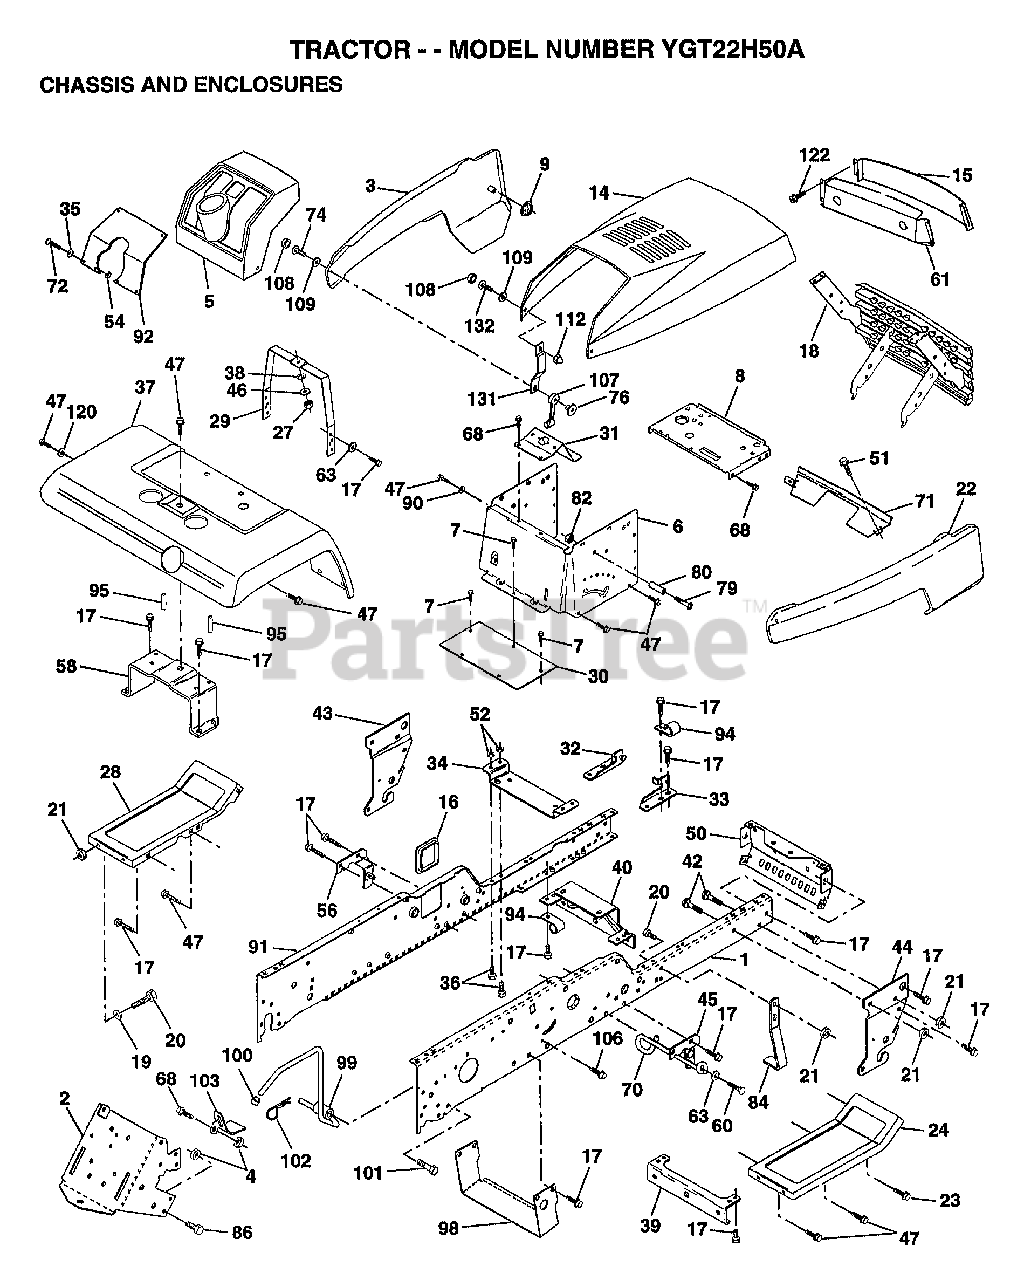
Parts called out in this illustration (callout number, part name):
1	"RAIL,FRAME RH"
2	DRAWBAR GT
3	"PANEL ASM-SIDE,LH"
4	NUT.7/16
5	DASHBOARD BLACK
6	DASH LOWER
7	SCREW
8	SUPPORT.DASH.BTRY
9	PAL NUT LT
14	"HOOD, YARD PRO"
15	LENS.BAR.CLEAR
16	COVER ACCESS
17	SCREW
19	WASHER
20	BOLT
22	"PANEL ASM SIDE,RH"
23	SCREW GTV
24	FOOTREST.RH.LT/GT
28	FOOTREST PNT LH
29	DASH.SUPT.YP/HUSQ
30	SADDLE.HYDRO.95
31	BRAKET.SUPT.STEER
32	BRACKET ASM FRAME
33	BRACKET ASM FRAME
34	BRACKET.ENG.SUPT.
35	WASHER
36	BOLT
37	"FENDER WS,FTK"
38	LOCKWASHER
39	BRACKET.AXLE.FRT.
40	"BRKT SUPPORT,AXLE"
43	BRACKET.SUS.FT.LH
44	BRACKET.SUS.FT.RH
45	BRACKET ASM., SUSP CHASSIS RH
46	WASHER PM
47	SCREW LT
50	"BRKT CHASSIS,FRNT"
51	SCREW CRT
56	BRACKET ASM., SUSP CHASSIS LH
58	BRKT.ASM.FENDER
60	SCREW
61	BEZEL.ASM.
63	WASHER
68	SCREW LT
70	GUIDE.BELT.MID.SP
72	SCREW
74	SCREW
76	WELDNUT
79	SCREW
80	SPACER LT
84	STOP.OVER.CENTER
86	BOLT
90	LOCKWASHER
91	"RAIL FRAME,LH"
92	"PLATE DASH,SLKSCR"
94	CLIP GTV
95	NUT-PUSH YT
98	BRACKET SKID CHAS
99	ROD BYPASS
101	SCREW LT
102	RETAINER M
103	LOCK BYPASS BRKT
107	HOOD LATCH T
108	SNAP CAP LT
109	WASHER LT
112	ACORN NUT RB
120	WASHER HYT
131	BKT.SPT.HOOD/PANL
132	SCREW.10-24X3/8.
